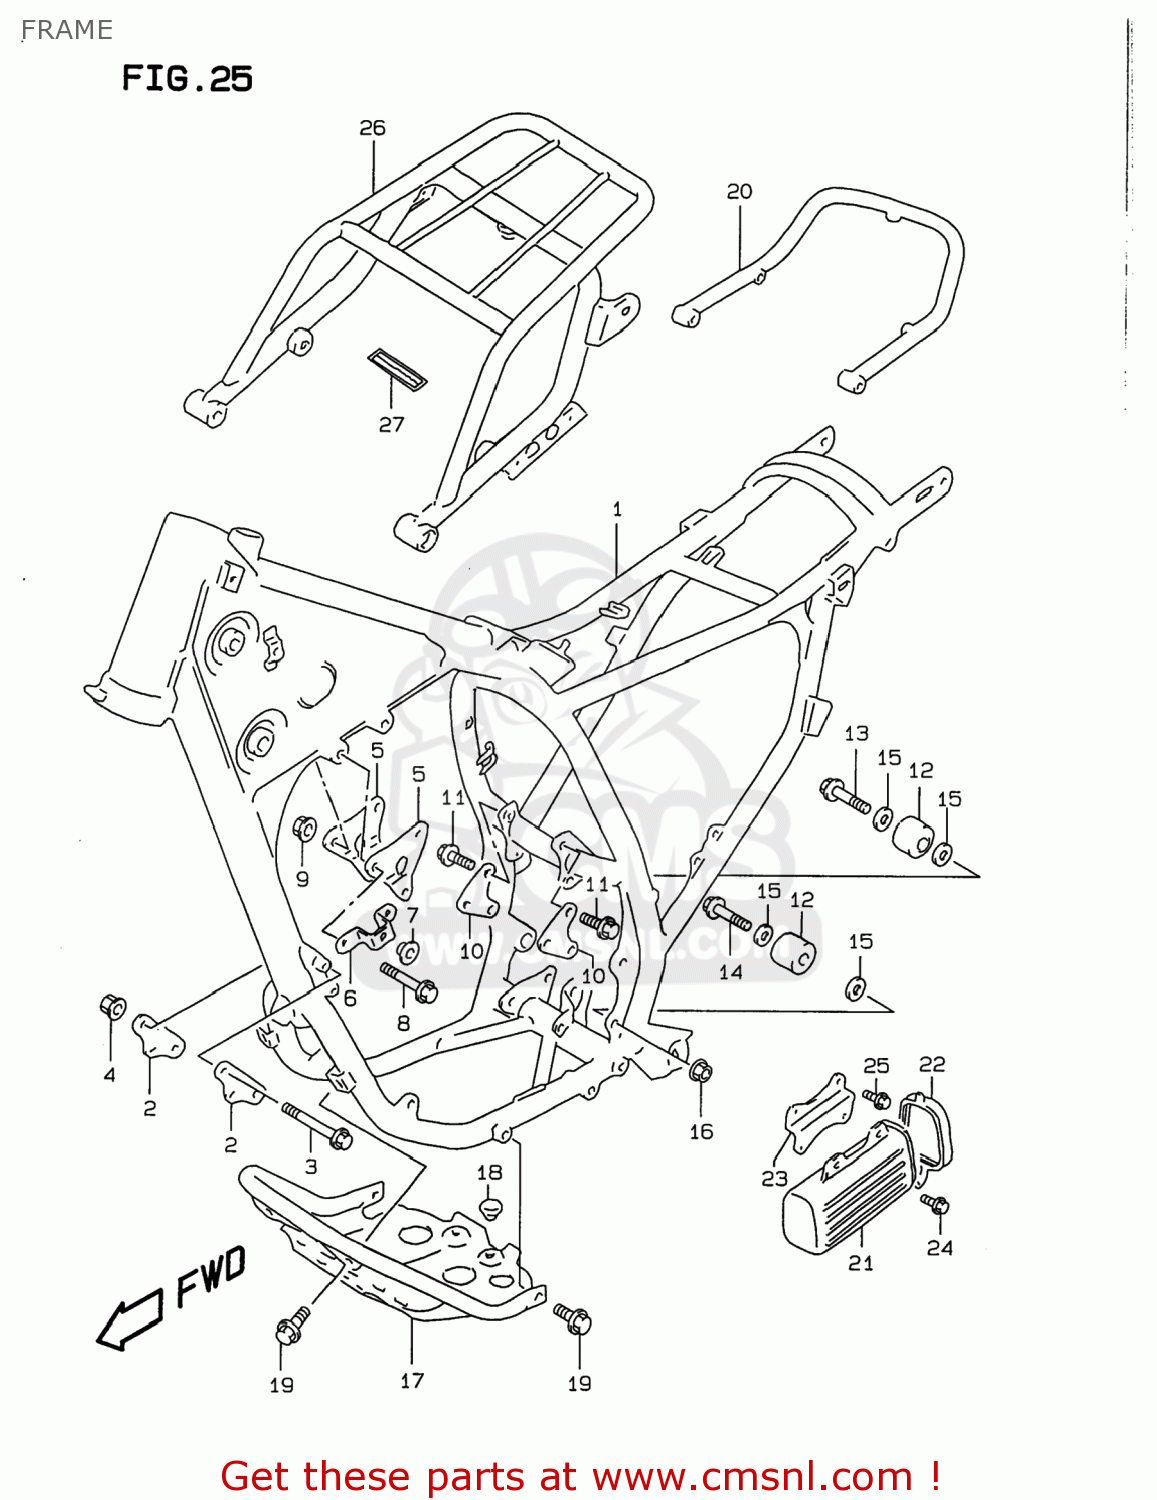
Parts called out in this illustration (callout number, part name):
1	FRAME COMP
2	PLATE,ENGINE MOUNT FR
3	BOLT(8X85)
4	NUT
5	PLATE,ENGINE MOUNT UPR
6	PLATE,FUEL TANK STOPPER
7	CUSHION
8	BOLT(8X70)
9	NUT
10	PLATE,ENGINE MOUNTING,REAR
11	BOLT(8X16)
12	ROLLER,CHAIN
13	BOLT(8X38)
14	BOLT 8X45
15	SHIM(8X12X1)
16	NUT
17	PROTECTOR,ENGINE(SILVER)
18	CUSHION
19	BOLT
20	GRIP,RR
21	HOLDER,TOOL
22	CAP,TOOL HOLDER
23	PLATE,TOOL HOLDER FITING
24	BOLT 6X16
25	BOLT
26	CARRIER,SPORT
27	LABEL,WARNING
